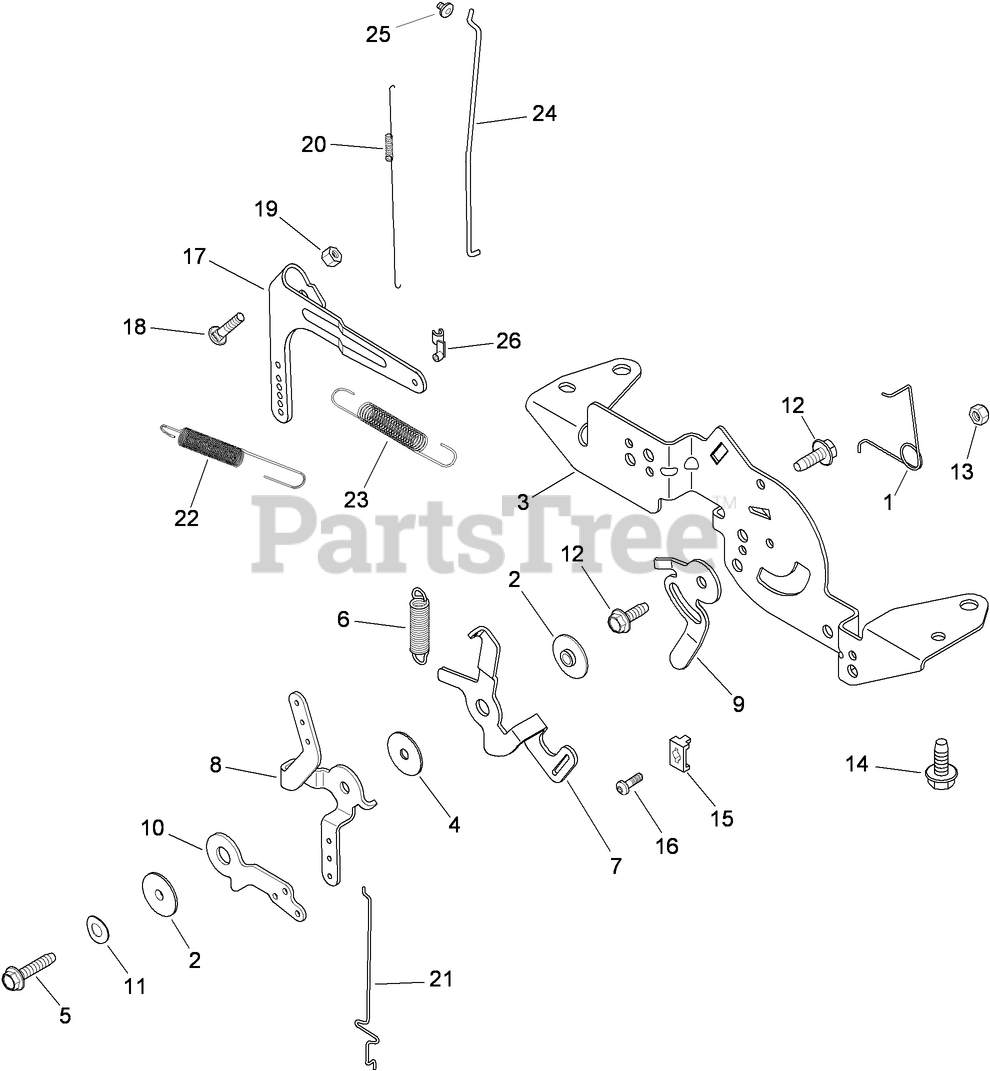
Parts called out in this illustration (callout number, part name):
1	SPRING-RETURN, CHOKE
2	CONTROL SPACER ASM
3	BRACKET-CONTROL
4	WASHER-FLAT (5.5MM)
5	SCREW-THREAD FORMING (M5x0.8x25mm)
6	SPRING-CONTROL, SPEED
7	LEVER-SPRING, GOVERNOR
8	LEVER-CONTROL, SPEED
9	LEVER-SETTING, SPEED
10	LEVER-CHOKE
11	WASHER-SPRING (1/4)
12	SCREW-FLANGE, THREAD FORMING (M5X0.8X16)
13	NUT-LOCK (M5X.8)
14	SCREW-FLANGE, THREAD FORMING (M6X1.0X16)
15	CLAMP-CABLE
16	SCREW-LBD, THD FRM (M5X0.8X16)
17	LEVER-GOVERNOR
18	BOLT-SQ NECK, RD HD (M6X1.0X25)
19	NUT-FLANGE (M6X1.0)
20	SPRING-LINKAGE
21	LINKAGE-CHOKE
22	Spring-Governor
23	SPRING-GOVERNOR
24	LINKAGE-THROTTLE
25	BUSHING-LINKAGE, THROTTLE
26	BUSHING-RETAINING, LINKAGE
